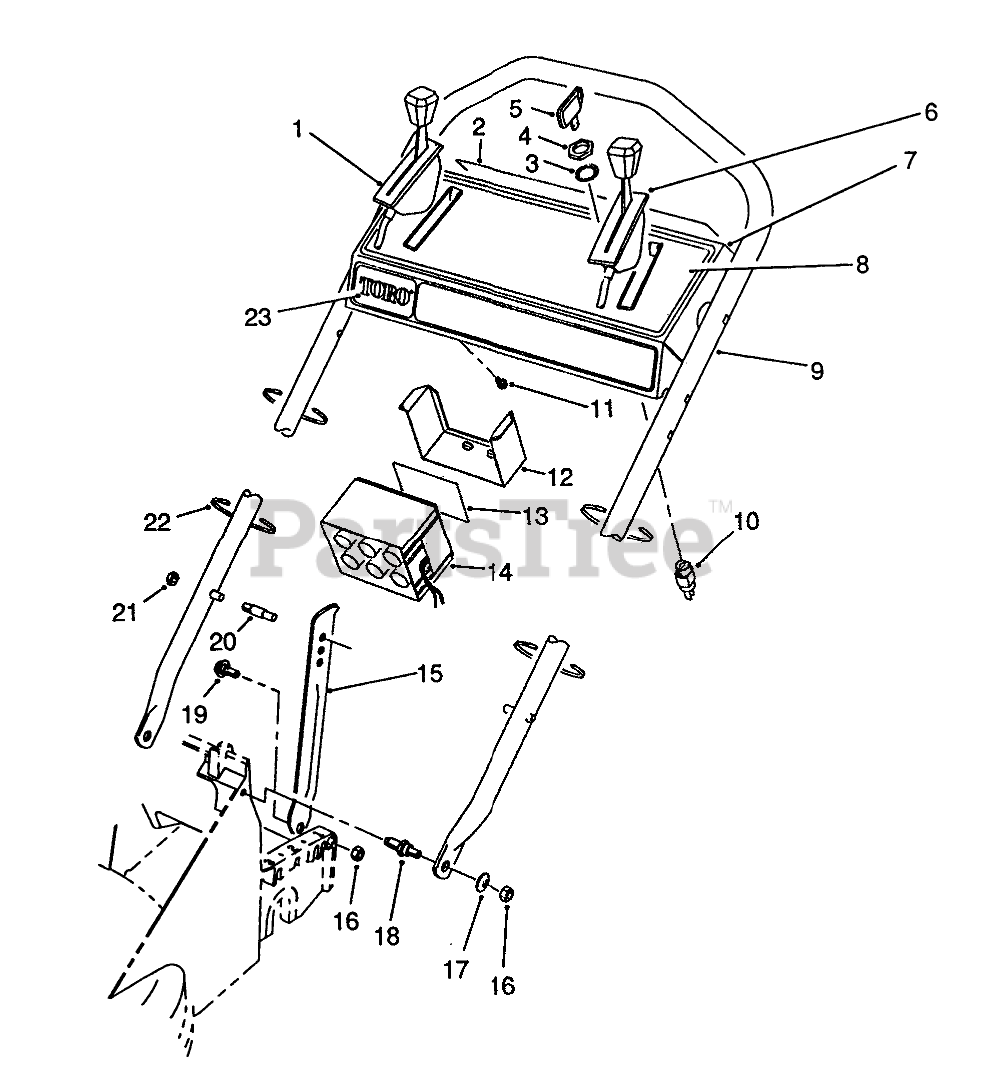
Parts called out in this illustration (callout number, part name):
1	Control-Ground Speed Bend Type #3 Sheath Lg. 51-1/4" Wire Lg. 2-1/8"
2	DECAL-PANEL, DANGER
3	WASHER-TOOTH, INTERNAL
4	NUT-HH
5	KEY-IGNITION
6	ControI-Throttle Bend Type #2 Sheath Lg. 44-3/4" Wire Lg. 2-1/2"
7	Panel-Control (Incl. Ref. #8) (Model No. 26624)
8	DECAL - CONTROL PANEL
9	HANDLE
10	Switch-Starter (Incl. Ref. #4 & 5)
11	SCREW-HWHTF
12	Retainer-Battery
13	Decal
14	Battery (Incl. Ref. #13)
15	HANDLE LATCH
16	NUT-LOCK, NI
17	WASHER-PLAIN
18	SCREW - SHOULDER STUD
19	SCREW - SHOULDER
20	HANDLE PIN
21	NUT-LOCK, NI
22	TIE-CABLE
23	DECAL - KEY LECTRIC
